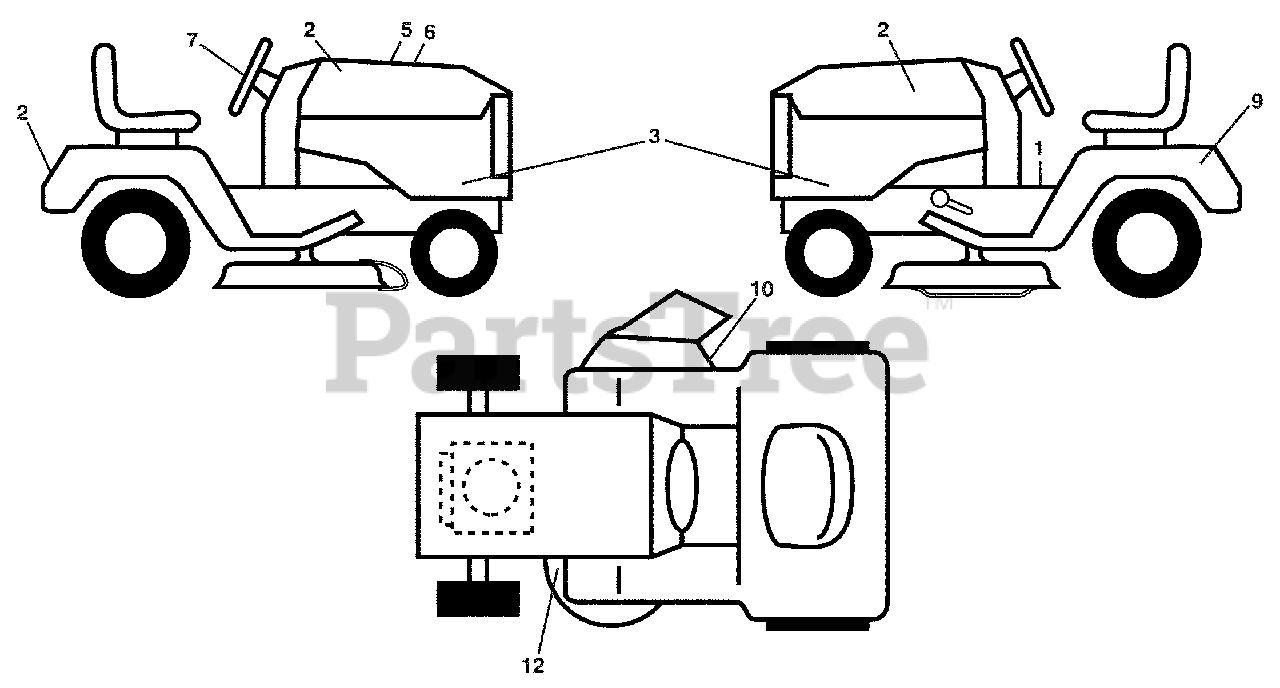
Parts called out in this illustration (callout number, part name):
1	Decal, Warning
2	Decal, Hood
3	Decal, Hood Panel SD
5	Decal, Customer Respons.
6	Decal, Replacement
7	Decal, Steering Wheel
9	Decal, Battery Dnge/Poi
10	Decal, Warning
12	Decal, Mower V-Belt Schematic
